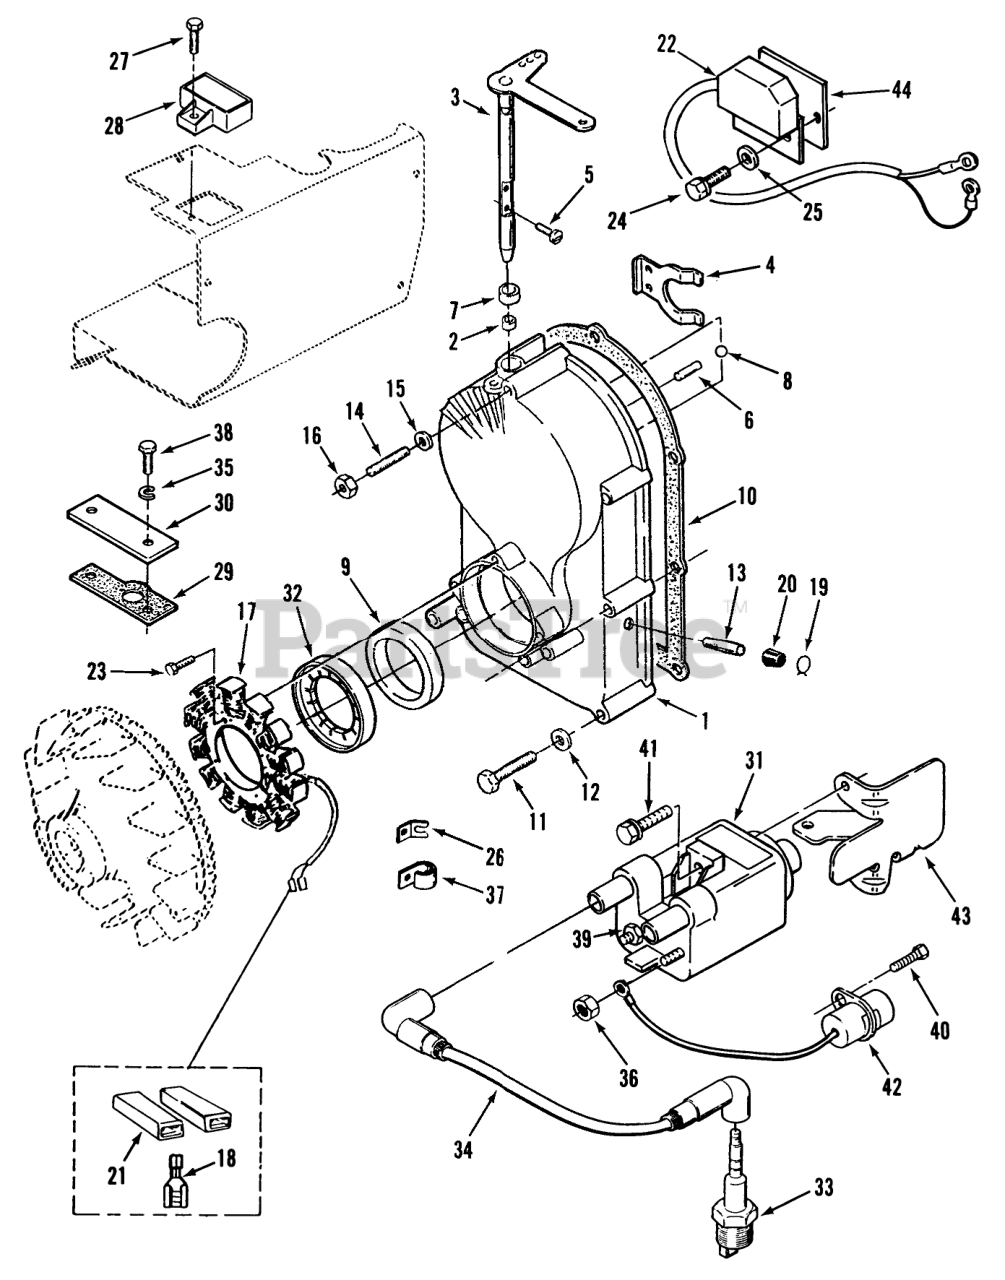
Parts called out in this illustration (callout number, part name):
1	Gearcase Kit (Includes items 2 thru 9)
2	Bearing
3	Governor Shaft & Arm Chromed
4	Yoke
5	Screw
6	Washer
7	Oil Seal
8	Bearing
9	Oil Seal
10	Gasket
11	Screw 5/16-18 1-3/4
12	Washer
14	Stud
15	Washer
16	Nut
17	STATOR
18	Stator Leads Terminal
19	Clamp
20	Cap
21	Terminal Connector Body Kit (Includes Terminals)
22	Control-Ignition
23	Screw Hex Hd. #10-32 x 1-1/2
24	Bolt
25	Lockwasher
26	Cable Clip
27	Hex Washer Hd. Cap Screw 1/4-20 x 1/4
28	Regulator
29	Gasket
30	Ignition Plunger Cover
31	Coil-Ignition
32	Rotor
33	Spark Plug
34	Wire-Plug
35	Washer-Lock
36	Nut
37	Clamp
38	Bolt
39	Nut
40	SCREW #10-32 X 5/8
41	Bolt
42	CONDENSER
43	Ignition Coil Bracket
44	Insulator
